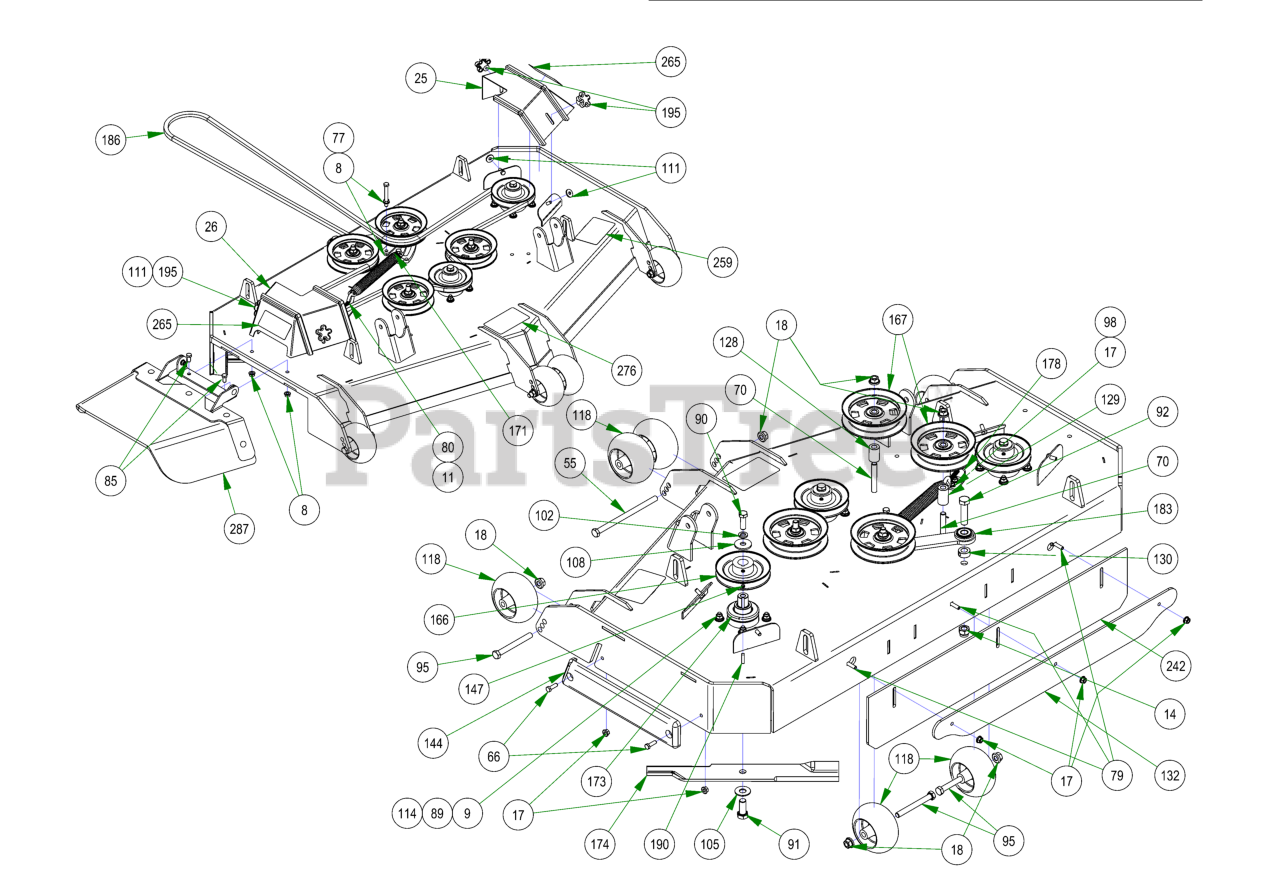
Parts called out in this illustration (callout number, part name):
8	3/8-16 HEX SERRATED FLANGE NUT HARD/ZINC
9	3/8-16 NYLON INSERT FLANGE LOCKNUT (GR.F) ZINC
11	3/8-16 HEX NUT ZINC
14	5/8-11 NYLON INSERT LOCKNUT ZINC
17	5/16-18 NYLON INSERT FLANGE LOCKNUT ZINC
18	1/2-13 NYLON INSERT FLANGE LOCKNUT ZINC
25	2019 54" Left Outlaw Gen2 Pulley Cover
26	2019 54" Right Outlaw Gen2 Pulley Cover
55	1/2-13 X 8 HEX CAP SCREW GR 5 ZINC
66	5/16-18 X 1 HEX CAP SCREW (GR.5) ZINC
70	1/2-13 X 3-1/2 HEX FLANGE BOLT (GR.8) ZINC
77	3/8-16 X 3 HEX CAP SCREW (GR.5) ZINC
79	5/16-18 X 1-1/4 CARRIAGE BOLT ZINC
80	4" 3/8-16 Eye Bolt
85	3/8-16 X 3/4 HEX CAP SCREW (GR.5) ZINC
89	3/8-16 X 1-1/2 HEX CAP SCREW (GR.5) ZINC
90	1/2-20 X 1-1/2 HEX CAP SCREW (GR.5) ZINC
91	5/8-18 X 1-1/2 HEX CAP SCREW (GR.8) ZINC YELLOW
92	5/8-11 X 2-1/2 HEX CAP SCREW (GR.5) ZINC
95	1/2-13 X 4-1/2 HEX CAP SCREW (GR.5) ZINC
98	5/16-18 X 7/8 CARRIAGE BOLT ZINC
102	1/2 SPLIT LOCKWASHER (GR.8) ZINC/YELLOW
105	5/8 USS FLAT WASHER (1-3/4" OD) GR.8 ZINC YELLOW
108	1/2 BELLEVILLE WASHER (1-5/8 OD X .140 THK) ZINC
111	.360 ID X .983 OD X .120 THICK FLAT WASHER NYLON
114	5/16 USS FLAT WASHER (7/8 OD) ZINC
118	2019 Deck Wheel
128	.502 ID X .750 OD X 1.500 Long Spacer
129	1 3/4" Pulley Spacer
130	5/8 SOLID SHAFT COLLAR (W/1 SET SCREW) ZINC
132	61 Bolt in Baffle Deck v2 Stripping Plate
144	REVISED TRIM BUMPER_20180226
147	5/16-24 X 1/4 SOCKET SET SCREW (CUP PT) PLAIN
166	5.25" Deck Spindle Pulley
167	5-3/4 Idler Pulley
171	2019 Outlaw Gen2 Deck Spring
173	OUTLAW SPINDLE ASSEMBLY
174	54" Fusion Blade for ZT/Mav/Outlaw/Revolt
178	2019 Deck Eye Bolt Tab
183	2019 Rebel Rogue Deck Idler
186	B165 Belt-60 54" deck Outlaw
190	1/4 X 1 SQ MACHINERY KEY 1018 STL PLN
195	5/16" Knob
214	2019 Sloped 54" Deck
242	R Series Rubber For Deck
259	2018 54" Deck Decal
265	Danger Decal-Spindle/Discharge
276	2019 Rebel & Rogue Deck Belt Route Decal
287	2019 Outlaw Gen2 Chute Assembly
